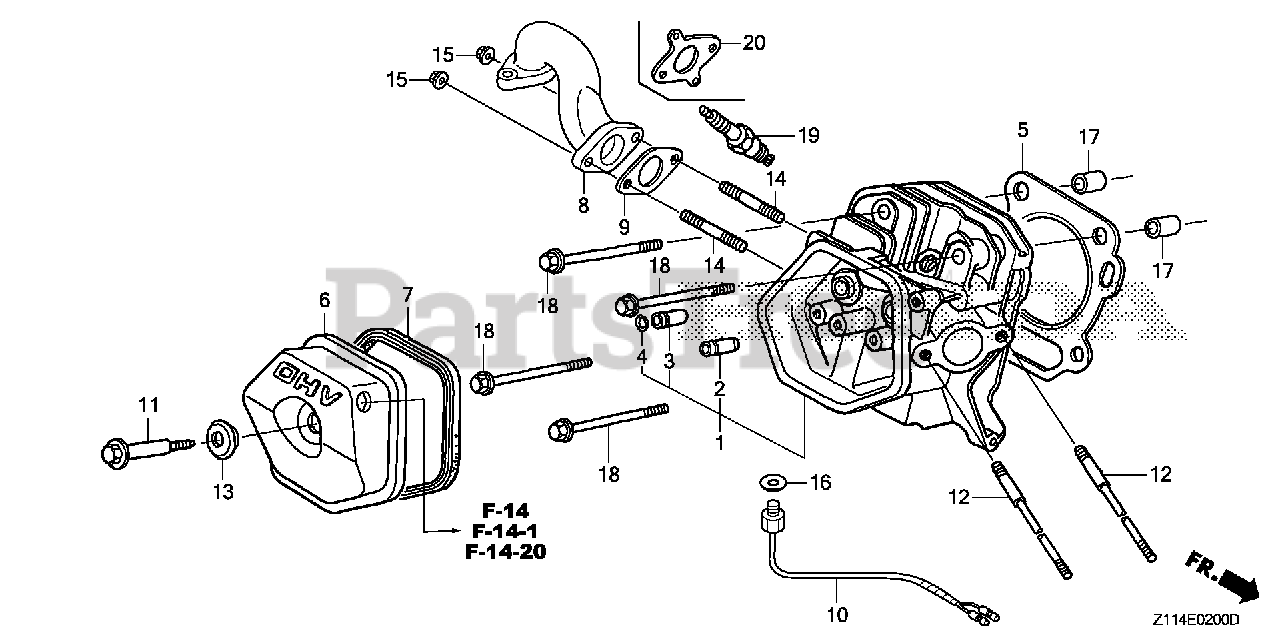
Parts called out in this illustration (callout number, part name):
1	CYLINDER HEAD
2	GUIDE, VALVE (OVER SIZE)
3	GUIDE, EX. VALVE (OVER SIZE)
4	CLIP, VALVE GUIDE
5	GASKET, CYLINDER HEAD (NIPPON LEAKLESS)
6	COVER, HEAD
7	GASKET, HEAD COVER
10	SENSOR ASSY., TEMPERATURE
11	BOLT, HEAD COVER
12	BOLT, STUD (8X126.5)
13	WASHER, HEAD COVER
14	BOLT, STUD (8X32)
15	NUT, FLANGE (8MM)
16	WASHER, PLAIN (8MM)
17	PIN, DOWEL (12X20)
18	BOLT, FLANGE (10X80)
19	SPARK PLUG (BPR5ES) (NGK)
19	SPARK PLUG (W16EPR-U) (DENSO)
20	GASKET, EX. PIPE
